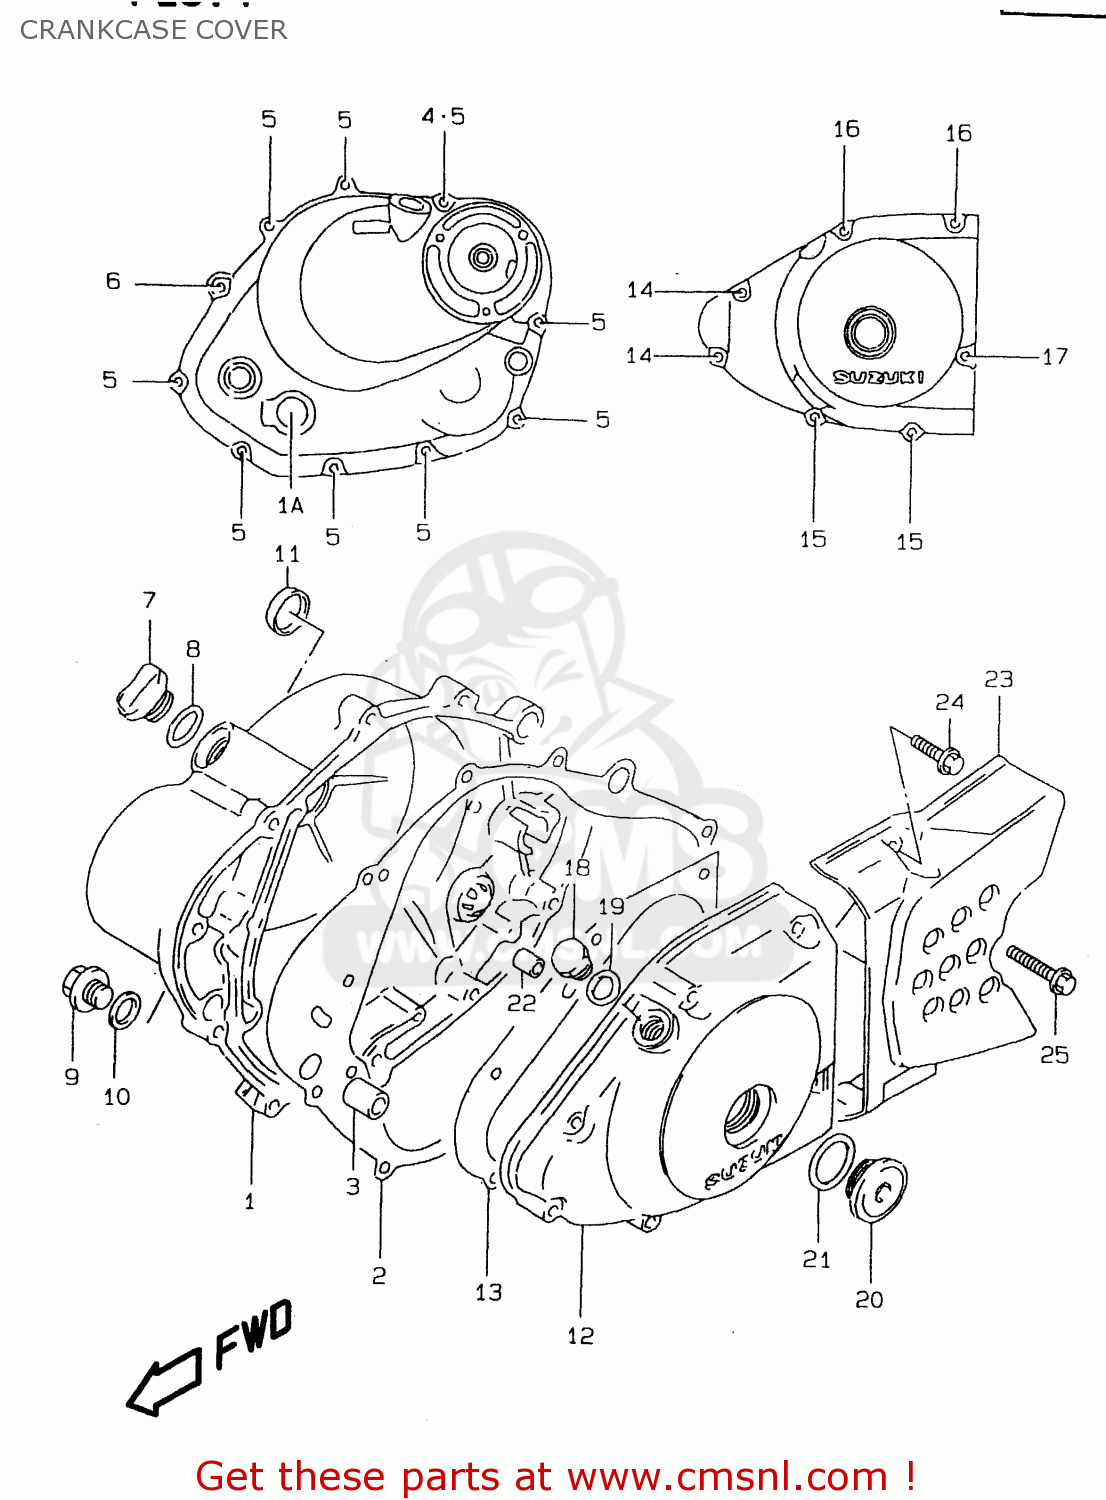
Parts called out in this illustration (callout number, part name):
1	COVER,CLUTCH
1A	LENS,OIL LEVEL CHECK
2	GASKET,CLUTCH COVER (NAS)
3	PIN
4	GASKET(5.8X11X1.2) (NAS)
5	BOLT,G/S SWITC
6	BOLT
7	PLUG
8	O RING(D:3.1,ID:16.8)
9	PLUG(14X12)
10	GASKET(13.8X18.8X4.8) (NAS)
11	PLUG,CLUTCH COVER KICK
12	COVER,MAGNETO
13	GASKET,MAGNETO COVER (NAS)
14	BOLT,G/S SWITC
15	BOLT
16	BOLT
17	BOLT
18	PLUG,12X9
19	GASKET(12.1X16.2X3.7) (NAS)
20	PLUG(26X9)
21	O RING(D:3.1,ID:22.7)
22	PIN
23	COVER,ENGINE SPROCKET
24	SCREW
25	BOLT
